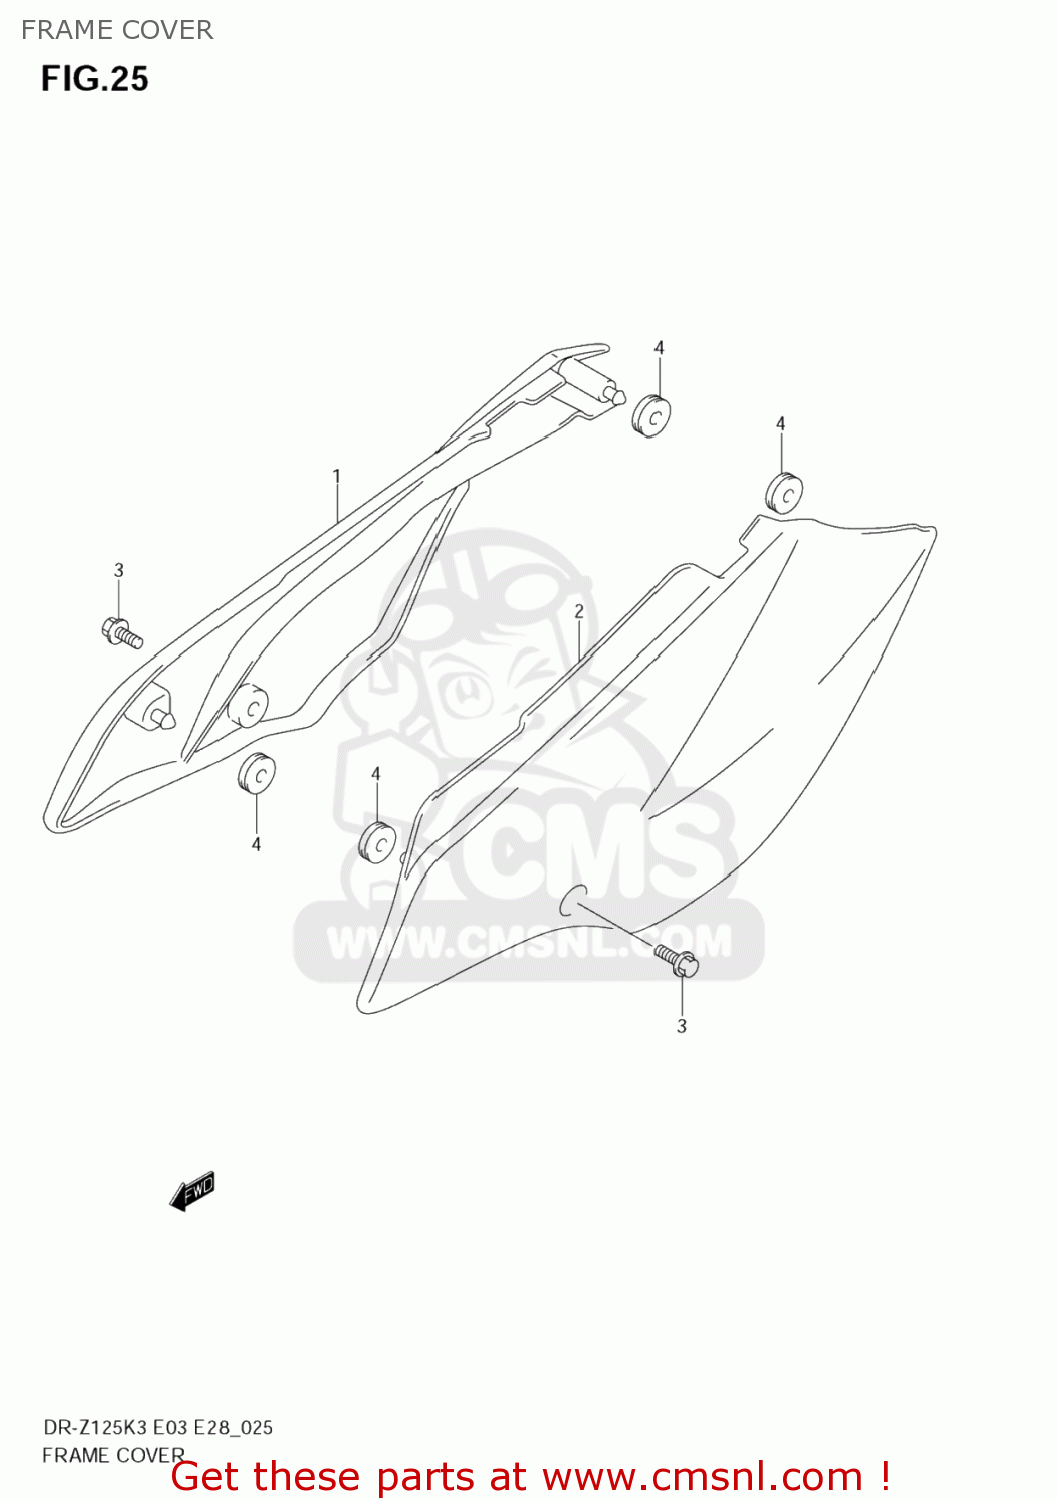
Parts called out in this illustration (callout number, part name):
1	COVER,FRAME,R(WHITE)
2	COVER,FRAME,L(WHITE)
3	BOLT
4	CUSHION
